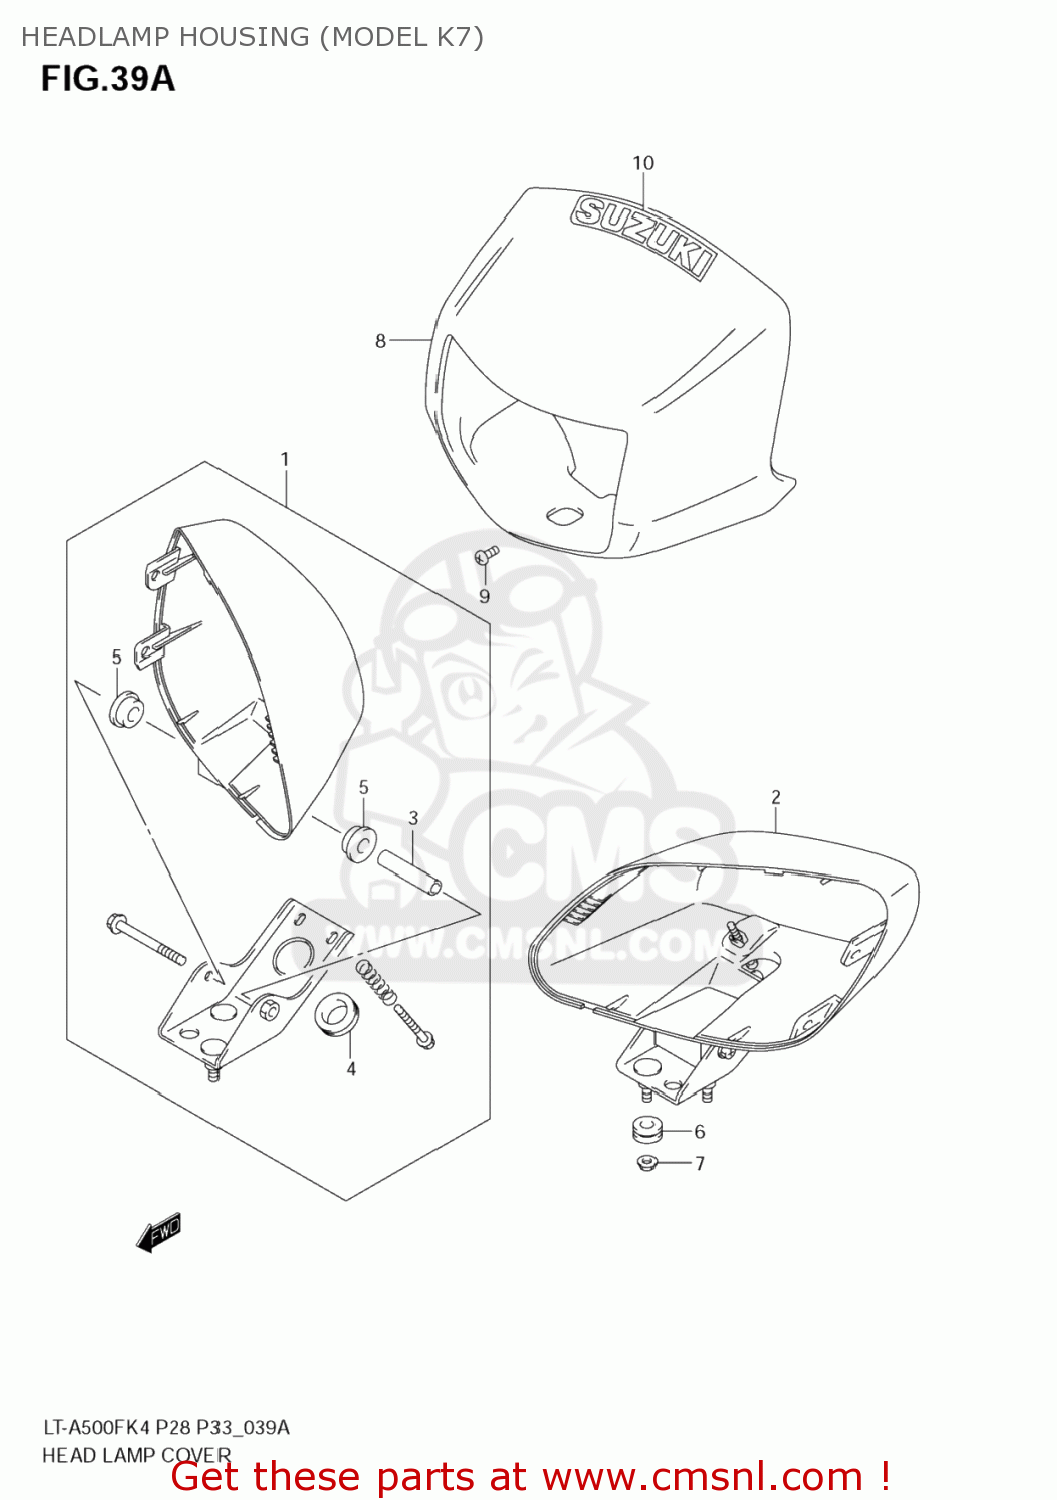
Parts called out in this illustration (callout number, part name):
1	HOUSING ASSY,HEADLAMP,R
2	HOUSING ASSY,HEADLAMP,L
3	SPACER(6.5X9X45.9)
4	CUSHION
5	CUSHION
6	CUSHION
7	NUT
8	COVER,HANDLE FR
9	SCREW
10	EMBLEM,SUZUKI
